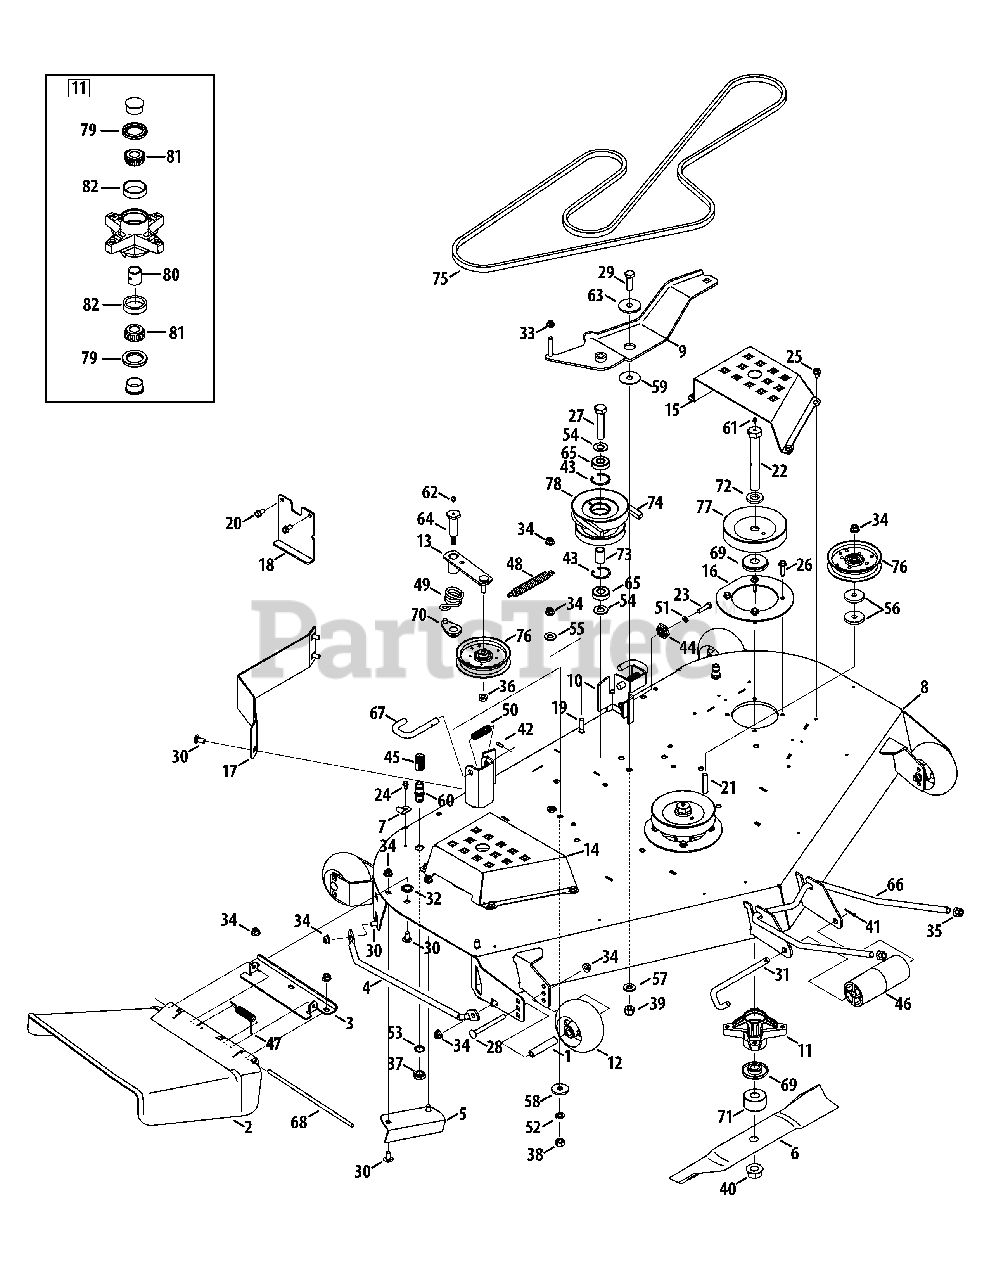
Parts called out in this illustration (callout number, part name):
1	Spacer, .390 x .620 x 3.04
2	Chute Deflector
3	Chute Deflector Bracket
4	Finger Guard
5	Micor Chute Baffle
6	Hi-Lift Blade, 19
7	Hook Retainer Bracket
8	Deck Assembly
9	PTO Idler Assembly
10	Hanger Adjustment Bracket
11	Spindle Assembly
12	Wheel, 5.0
13	Idler Arm Assembly
16	Spindle Reinforcement Plate
17	Baffle
18	Up-Stop Bracket
19	Carriage Bolt, 3/8 x 16 x 1.50
20	Hex Washer Screw, 5/16-18 x .750
21	Carriage Bolt, 3/8-16 x 2.50
22	Hex Screw, 3/4-16 x 6.00
23	Hex Screw, 5/16-18 x 1.25
24	Hex Washer Screw, 1/4-20 x .500
25	Hex Washer Screw, 5/16-18 x .625
26	Hex Washer Screw, 5/16-18 x 1.250
27	Hex Screw, 5/8-18 x 3.00
28	Carriage Screw, 3/8-16 x 4.25
29	Hex Screw, 1/2-20 x 1.50
30	Carriage Bolt, 3/8-16 x .75
31	Roller Pin, 1/2 x 7.31
32	Push Nut, 3/8
33	Flange Lock Nut, 5/16-18
34	Flange Lock Nut, 3/8-16
35	Flex Lock Nut, 1/2-13
36	Flange Lock Nut, 3/8-16
37	Hex Nut, M16-1.5
38	Hex Nut, 7/16-14
39	Hex Lock Nut, 1/2-20
40	Flange Lock Nut, 3/4-16
41	Cotter Pin, 3/32 x 1.25
42	Spirol Spring Pin
43	Retainer Ring
44	Deck Adjustment Gear
45	Water Nozzle Adapter
46	Front Roller
47	Torsion Spring, 180 x .639 x 2.16 x .12
48	Extension Spring, 1.0 x 6.140
49	Idler Torsion Spring, 1.10 x 1.3
50	Compression Spring, .66 x 1.8
51	Lock Washer, 5/16
52	Lock Washer, 7/16
53	Lock Washer, 5/8
54	Flat Washer, .650 x 1.250 x .075
55	Flat Washer, .510 x 1.000 x .125
56	Flat Washer, .4375 x 1.75 x .25
57	Flat Washer, .531 x 1.062 x .134
58	Flat Washer, .45 x 1.5 x .172
59	Flat Washer, .535 x 1.92 x .060
60	Deck Water Nozzle
61	Grease Fitting, 1/4-28 x 3/16
62	Drive Lube Fitting, 3/16
63	Shoulder Spacer, .9790 x .2025
64	Shoulder Screw, 7/16-14 x .68 x 2.11
65	Ball Bearing, .625 x 40 x 12
66	Front Hanger Rod
67	Mower Support Pin
68	Chute Deflector Rod
69	Spindle Deck Spacer
70	Retainer Spring
71	Spindle Spacer, .760 x 2.0 x 1.10
72	Spacer, .812 x .218
73	Spacer, .88 x .635 x 1.25
76	Idler Pulley
78	Double Pulley
80	Bearing Spacer, .78 x 1.0 x 1.0425
81	Cone Bearing, .750
82	Bearing Cup, .750
